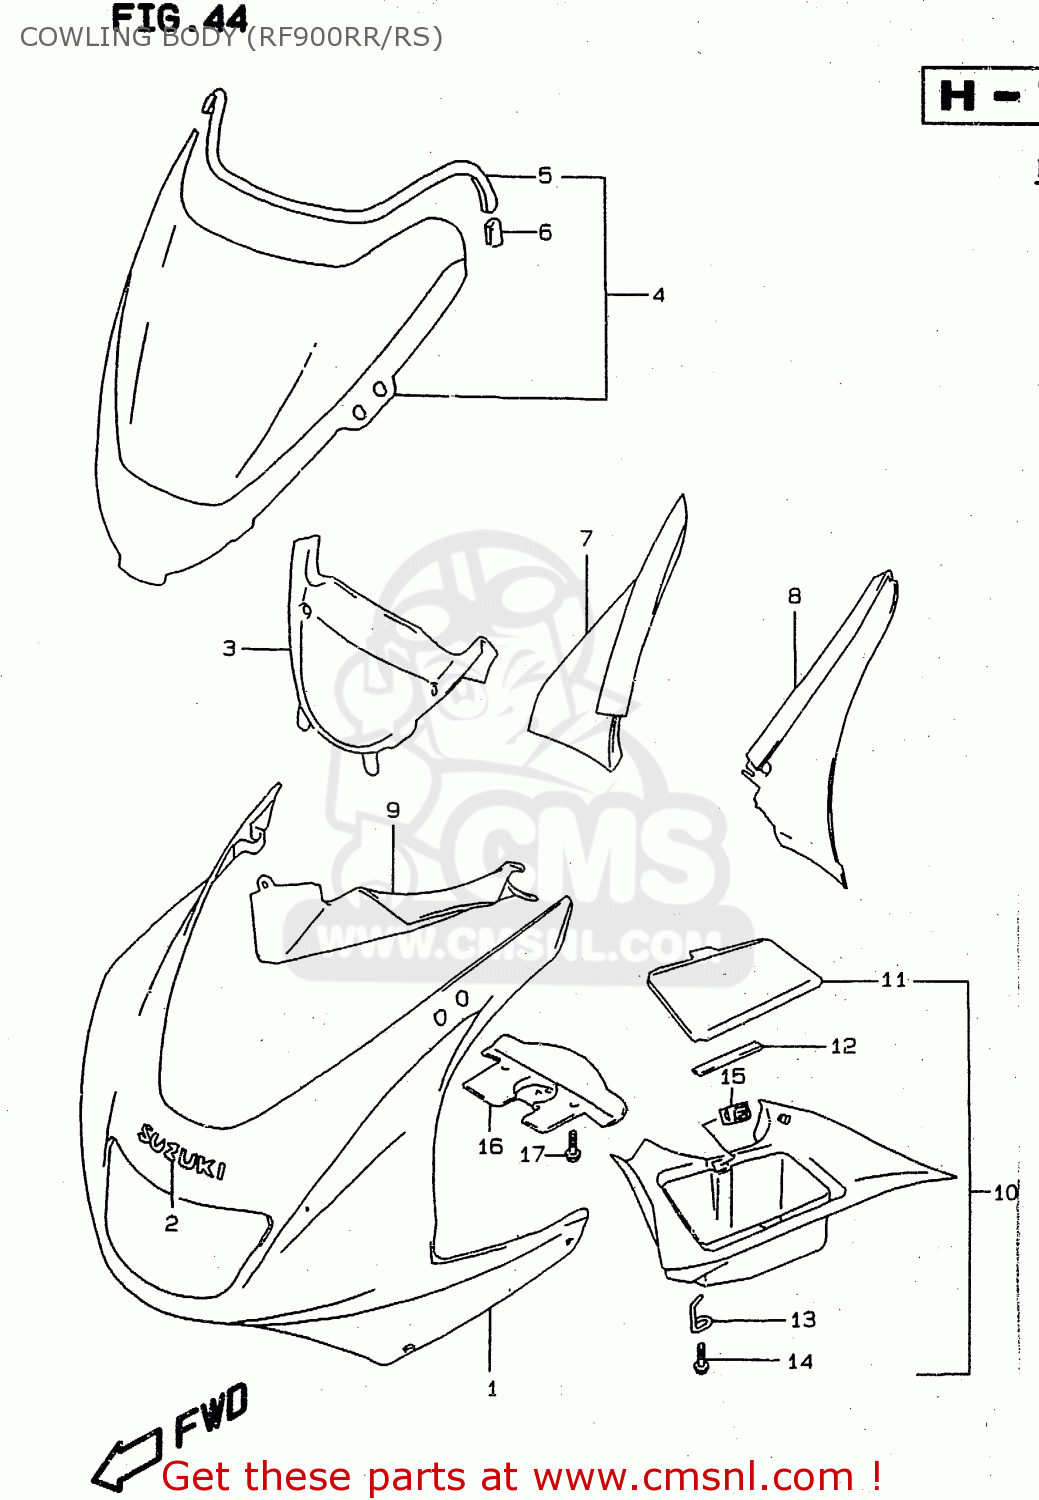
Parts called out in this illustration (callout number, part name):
1	COWLING ASSY,BODY
2	EMBLEM,SUZUKI
3	PANEL,COWLING CTR
4	WINDSCREEN SET
5	MOLDING WINDSCREEN
6	CLIP,WINDSCREEN MOLDING
7	PANEL,UPR,R
8	PANEL,UPR,L
9	PANEL,SIDE,R
10	PANEL ASSY,SIDE,L
11	LID,PANEL BOX
12	CUSHION,LID
13	HINGE,PANEL LID
14	SCREW
15	LOCK,I/P CTR BOX
16	COVER,COWLING FR LWR
17	BOLT(6X12)
